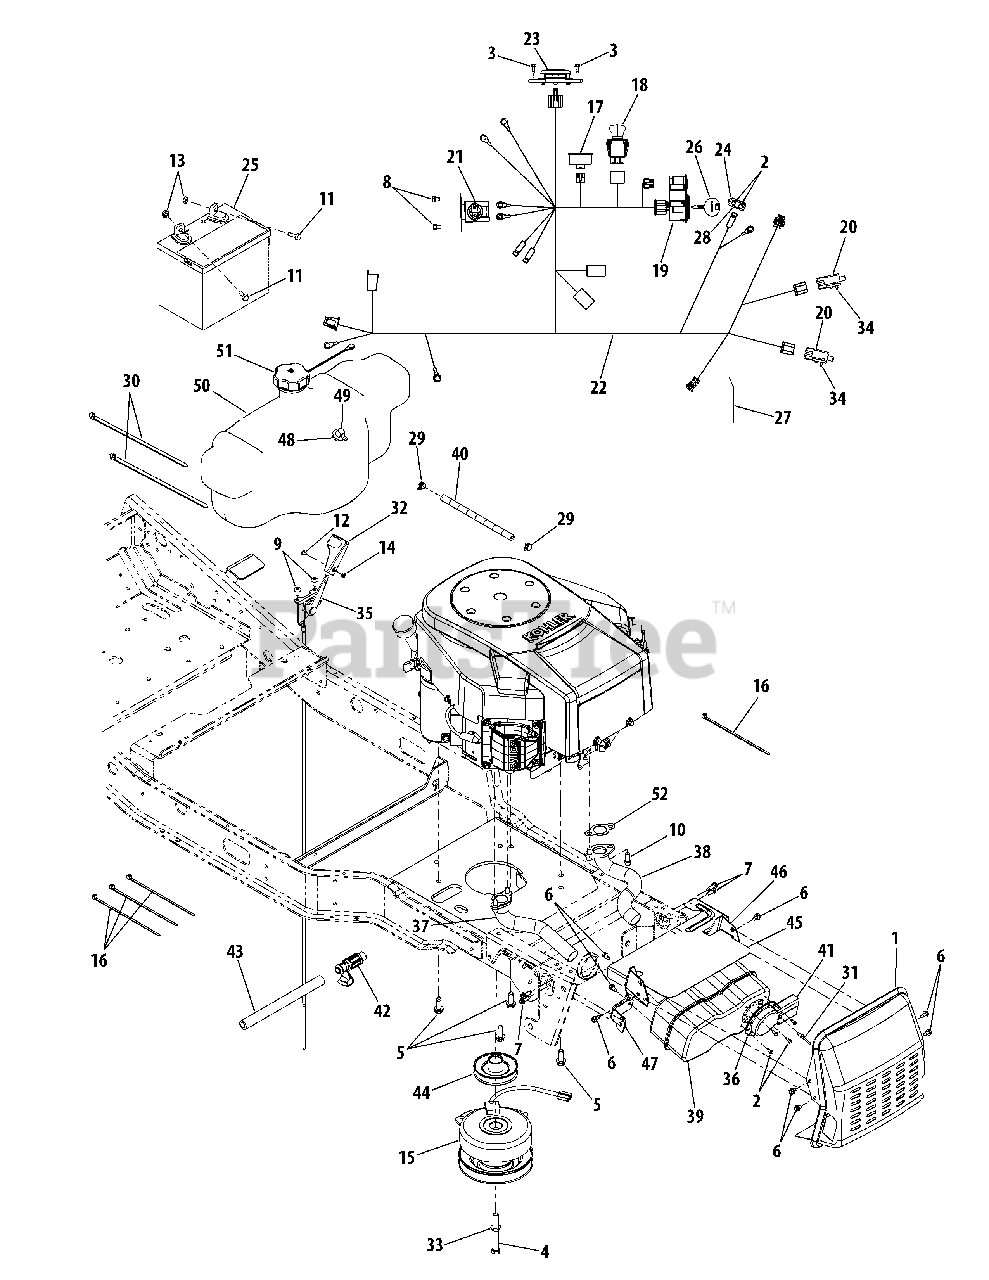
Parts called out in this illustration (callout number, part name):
2	Screw, Hex Wash. Hd. Tapp, #8-18 x .5
3	Screw, Hex Wash. Hd. Tapp, #12-16 x .5
4	Screw, Hex Cap Lock, 7/16-20 x 3.5 Gr5
5	Screw, Hex Wash. Hd. Tapp, 3/8-16 x 1.0
6	Screw, Hex Wash. Hd. Tapp, 1/4-20 x .5
7	Screw, Hex Wash. Hd. Tapp, 1/4-20 x .75
8	Screw, Hex Wash. Hd. Tapp, 1/4-20 x .375
9	Screw, Truss Hd. Torx, 1/4-14 x .625
10	Screw, Socket Hd., 5/16-18 x .75
11	Screw, Hex Cap, 1/4-20 x .75 Gr5
12	Screw, Truss Hd. Phillips Mach., #8-32 x .375
13	Nut, Sems, 1/4-20
14	Nut, Hex, #8-32 GrA
15	Clutch, Electric PTO
16	Tie, Cable, 3/16 x 7.4
17	Meter, Indicator/Hour
18	Switch, Electric PTO
19	Module, Key Switch
20	Switch, Interlock
21	Solenoid
22	Harness, Wire
23	Switch, Seat
24	Switch, Spring
26	Key, Ignition
27	Tie, Cable
28	Plate, Insulator
29	Clamp, Hose
30	Tie, Cable
31	Rivet, Pop, .188 x .3
32	Knob, Throttle Control
33	Washer, Lock, 7/16
34	Screw, Shoulder, #10-32 x .5
35	Cable, Throttle Control, 41.5 Long
36	Defl ector, Muffler
37	Pipe, Exhaust RH
38	Pipe, Exhaust LH
39	Muffler, Dual Inlet
40	Hose, Fuel Line
41	Deflector, Muffler
42	Valve, Oil Drain
43	Hose, Oil Drain Extension
44	Pulley, Engine
45	Shield, Heat
49	Fitting, Fuel Pickup
50	Tank, Fuel, 3.5 Gallon
51	Cap, Fuel
52	Gasket, Exhaust
